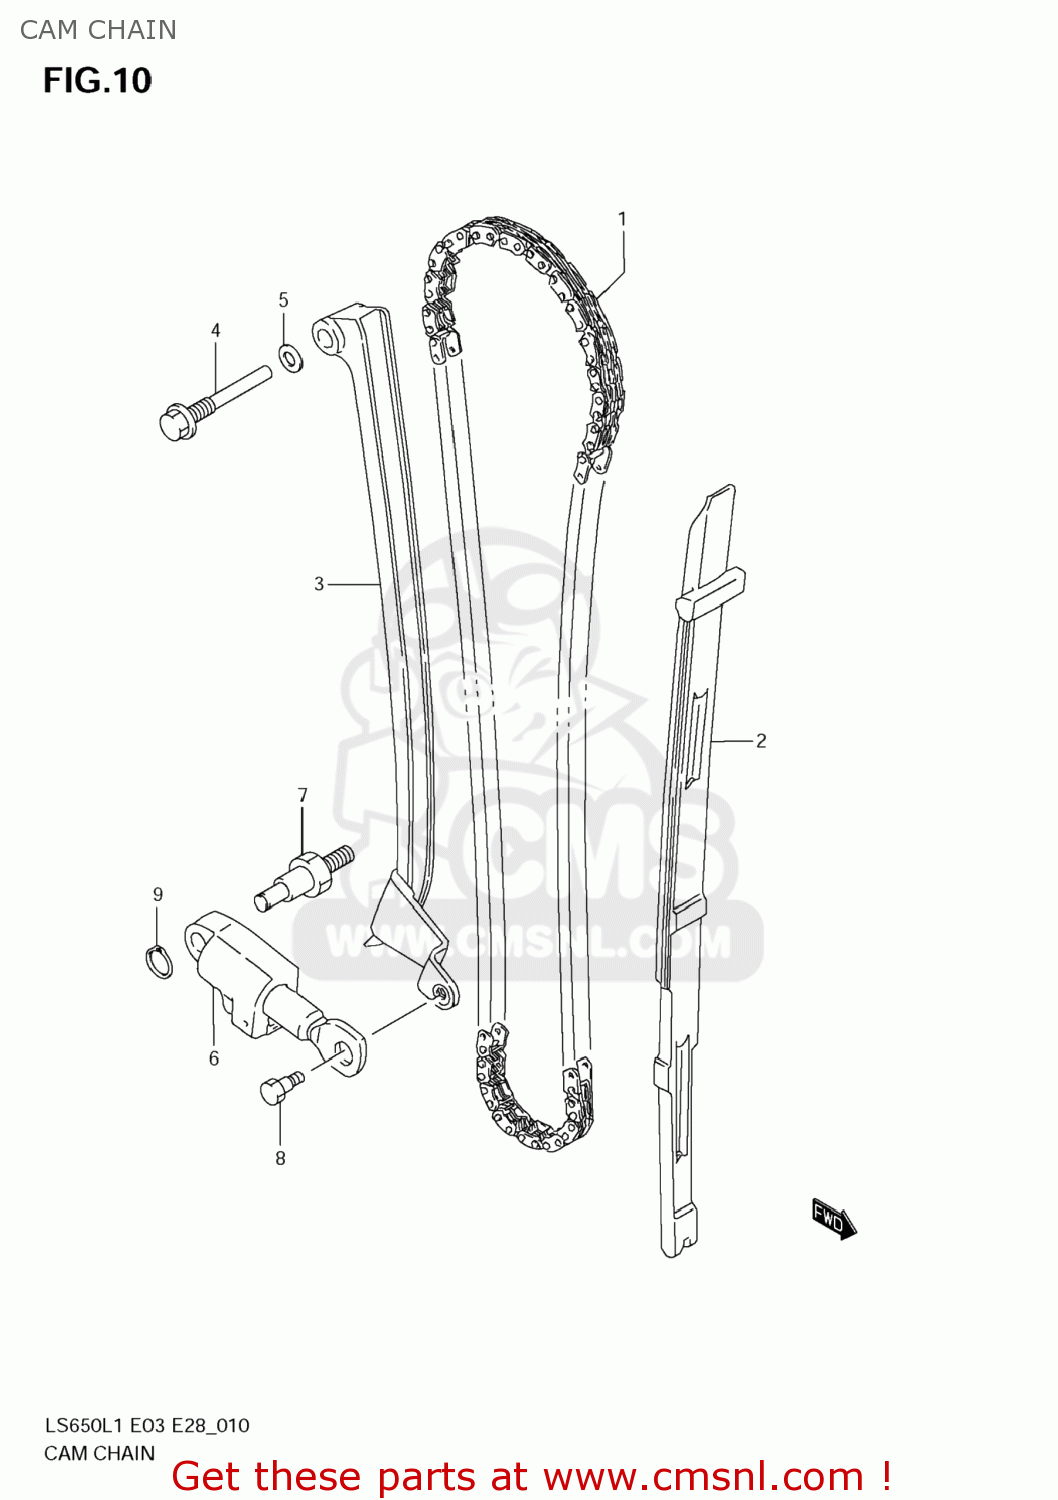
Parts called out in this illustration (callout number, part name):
1	CHAIN,CAMSHAFT DRIVE
2	GUIDE,CAM CHAIN
3	TENSIONER,CAM CHAIN
4	BOLT,CAM CHAIN TENSIONER
5	GASKET(8.2X14X1) (NAS)
6	ADJUSTER ASSY,TENSIONER
7	BOLT,STUD
8	BOLT
9	CIRCLIP
